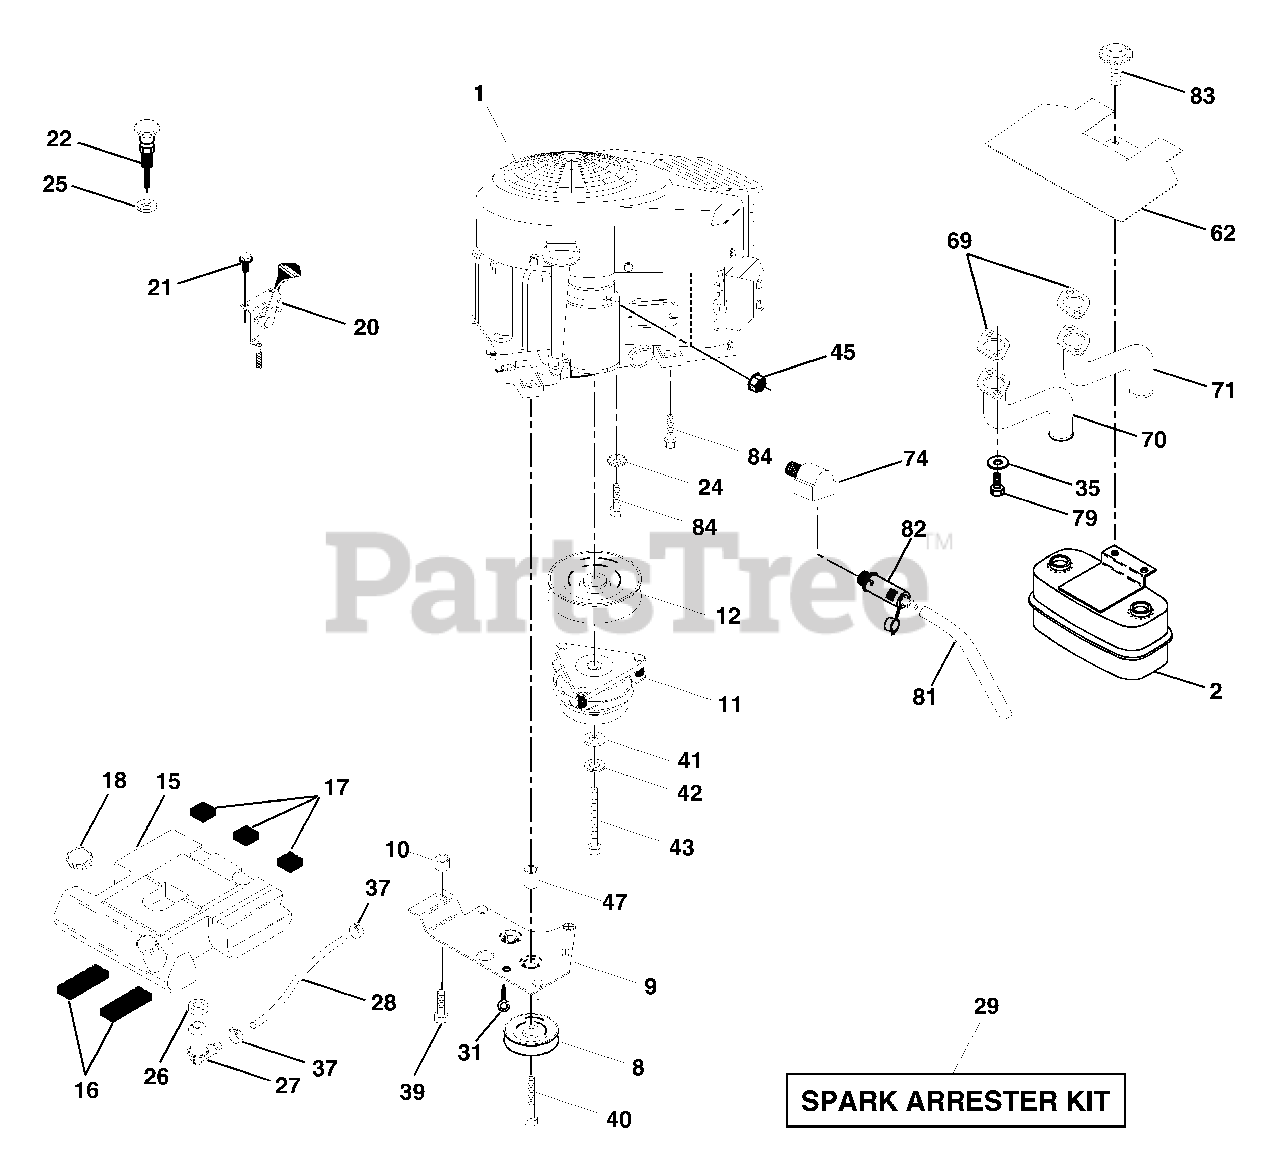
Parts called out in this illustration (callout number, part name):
2	Muffler Side
8	Pulley V-Idler
9	Keeper Asm. Belt Engine VGT
11	Clutch Electric
12	Pulley Engine VGT Elect Clutch
15	Tank Fuel Rear 5.0
16	Pad Spacer
17	Pad Spacer
18	Cap Fuel
20	Control Throttle
21	Screw Hex Thd Cut 1/4 - 20 X 5/8
22	Control Choke
24	Washer Ext Tooth 3/8
25	Nut Keps 3/8-24 Unf
27	Stem Tank Fuel
28	Fuel Line
29	Spark Arrester Kit
31	Clip Push-In Hinged
35	Washer
37	Clamp Hose
39	Screw TT 3/8-16 x 2-1/4 UNC
40	Screw TT 3/8-16 x 4 UNC
41	Washer 1-1/2 OD X 15/32 ID X .250
42	Washer Lock 7/16
43	Bolt Hex 7/16-20 X 3.75 Ga 5
62	Shield Heat Muffler
70	Tube Exhaust LH
71	Tube Exhaust RH
74	Elbow Street Brass
79	Screw 5/16-18 x 3/4
80	Nut Flange M8-1.25
81	Tube Drain Oil Easy
82	Plug Oil Drain
83	Bolt 5/16-18unc X 1-3/4 W/Sems
84	Screw 3/8-16 x 1-1/2
